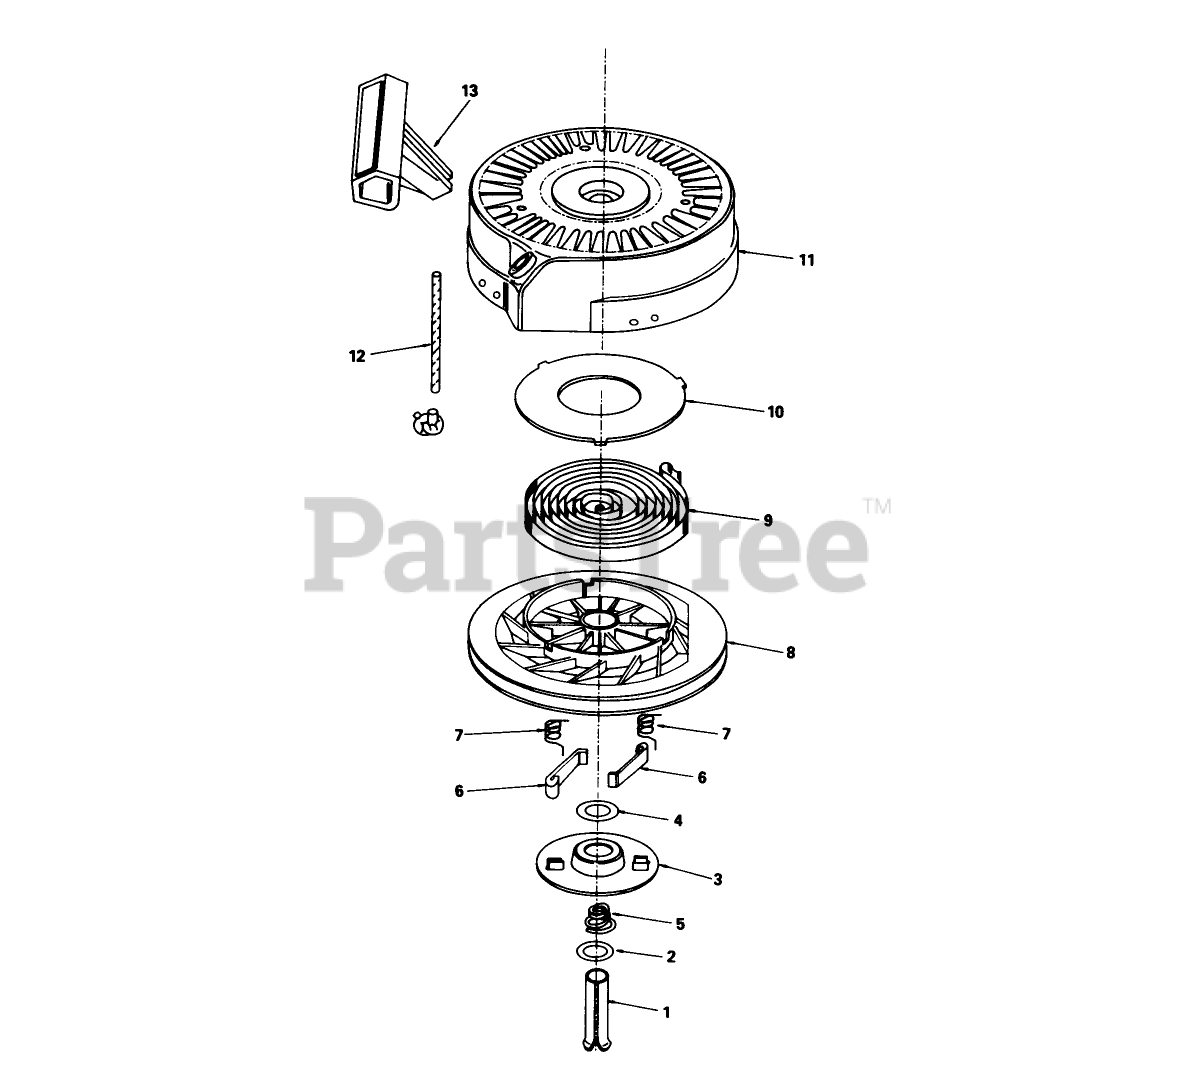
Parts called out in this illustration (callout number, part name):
1	Pin-Spring (Incl. Ref. #4)
3	Retainer
5	Brake Spring
6	Dog-Starter
7	Spring-Dog
8	Pulley
9	Rewind Spring
10	Cover-Spring
11	Housing-Starter
12	Rope-Starter (98 cut to length)
13	Handle-Starter
